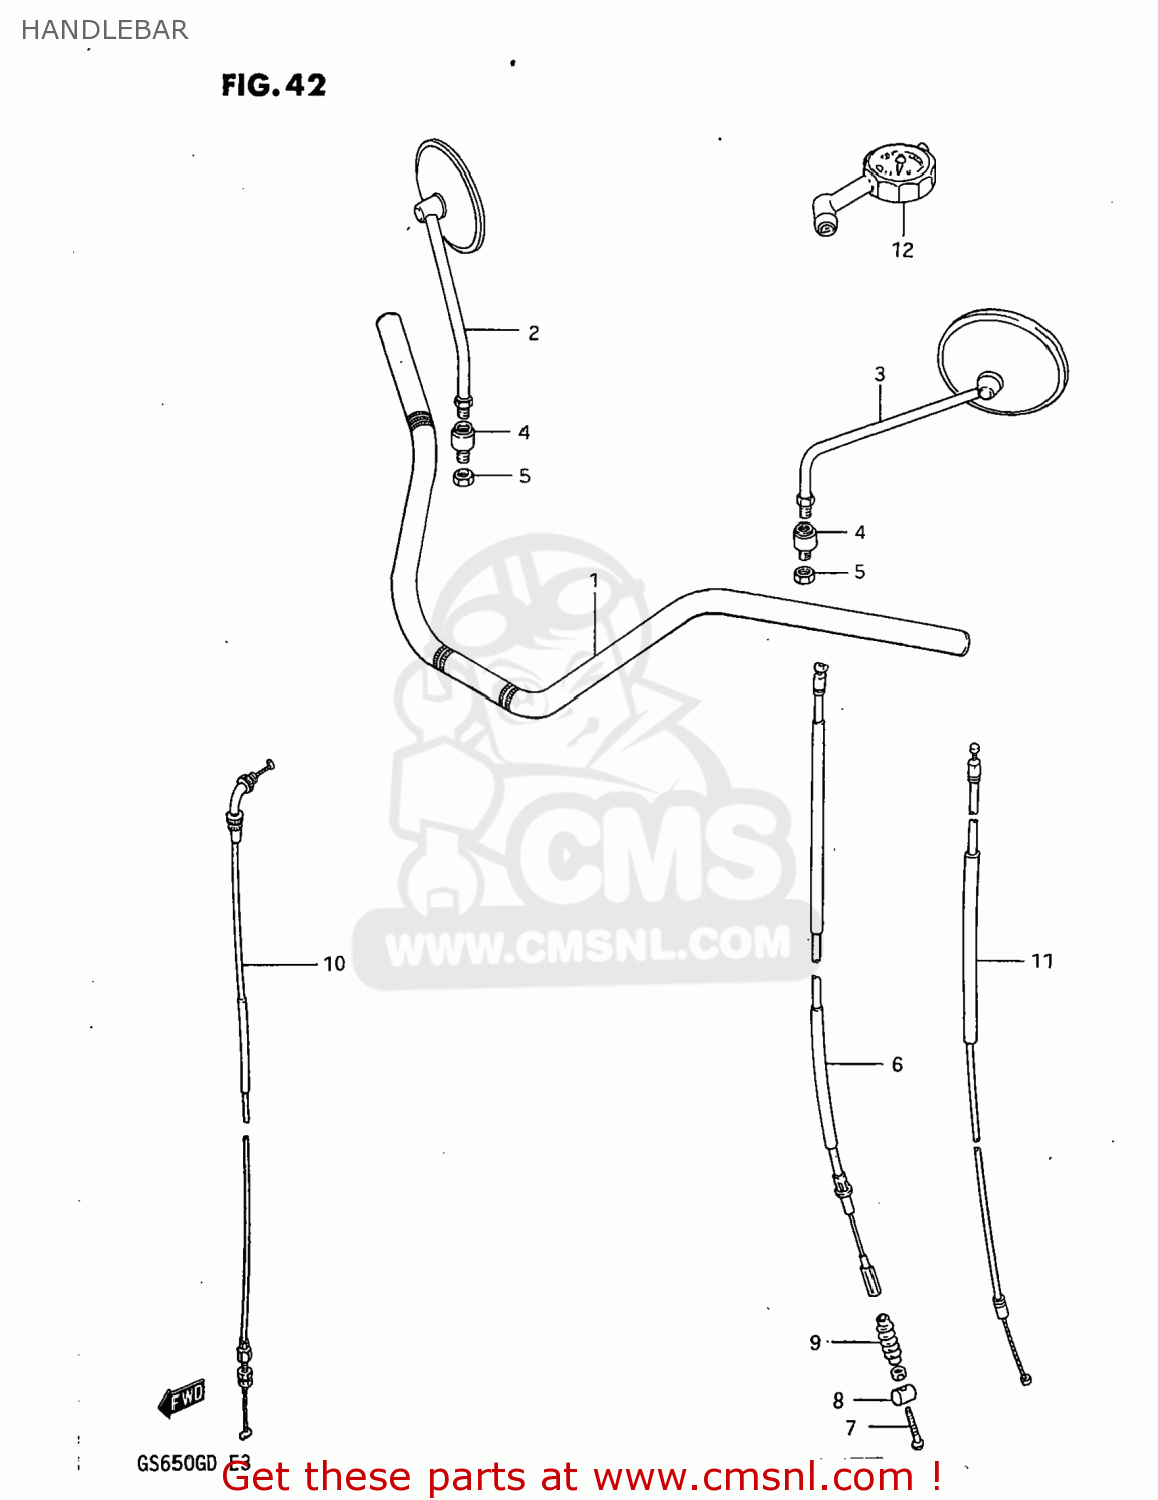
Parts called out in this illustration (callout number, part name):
1	HANDLEBAR
2	MIRROR ASSEMBLY,RIGHT
3	MIRROR ASSEMBLY,LEFT
4	CUSHION,REAR VIEW MIRROR
5	NUT
6	CABLE ASSEMBLY,CLUTCH
7	SCREW
8	PIN
9	SEAL,DUST(6.5X16X91)
10	CABLE ASSEMBLY,THROTTLE
11	CABLE COMP,STARTER
12	GAUGE ASSY,AIR PRESSURE
